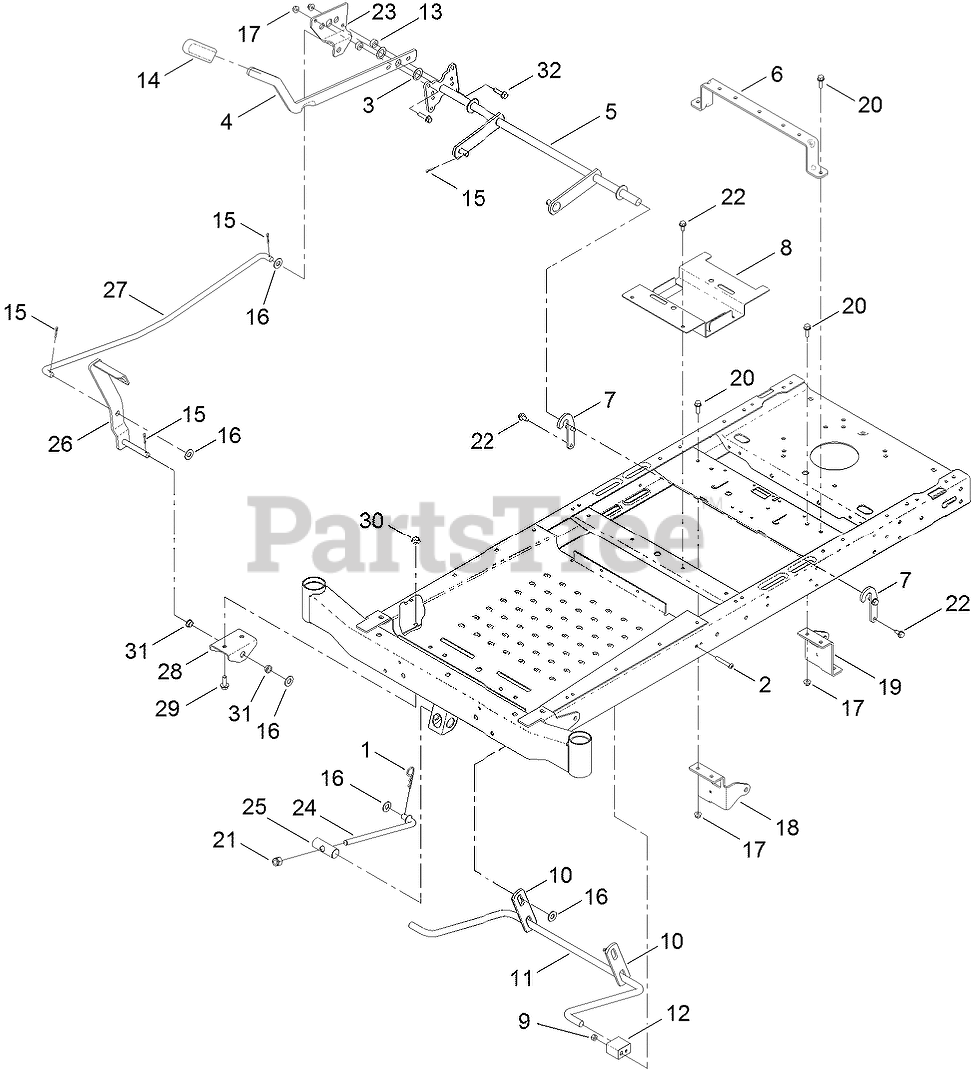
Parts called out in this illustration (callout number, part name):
1	PIN-COTTER
2	SCREW-HSBH
3	WASHER-THRUST
4	LEVER-LIFT
5	LIFT-DECK, WIDE
6	BRACE-SEAT, REAR
7	BRACKET-LIFT
8	BRACKET-BATTERY
9	NUT-LOCK, NI
10	LINK-LIFT
11	ARM-LIFT, REAR (WIDE)
12	BLOCK-PIVOT
13	SPACER
14	GRIP-LEVER
15	PIN-COTTER
16	WASHER-FLAT
17	NUT-HF, NI
18	MOUNT-HYDRO, FRONT (RH)
19	MOUNT-HYDRO, FRONT (LH)
20	SCREW-HHF
21	NUT-HEX
22	SCREW-HWHTF
23	PLATE-FOOTLIFT
24	ROD-TRUNION
25	PIN-PIVOT
27	ROD-FOOTLIFT
28	BRACKET-FOOTLIFT
29	SCREW-HHF
30	NUT-HF, NI
31	BUSHING-FLANGE
32	SCREW-HHF
